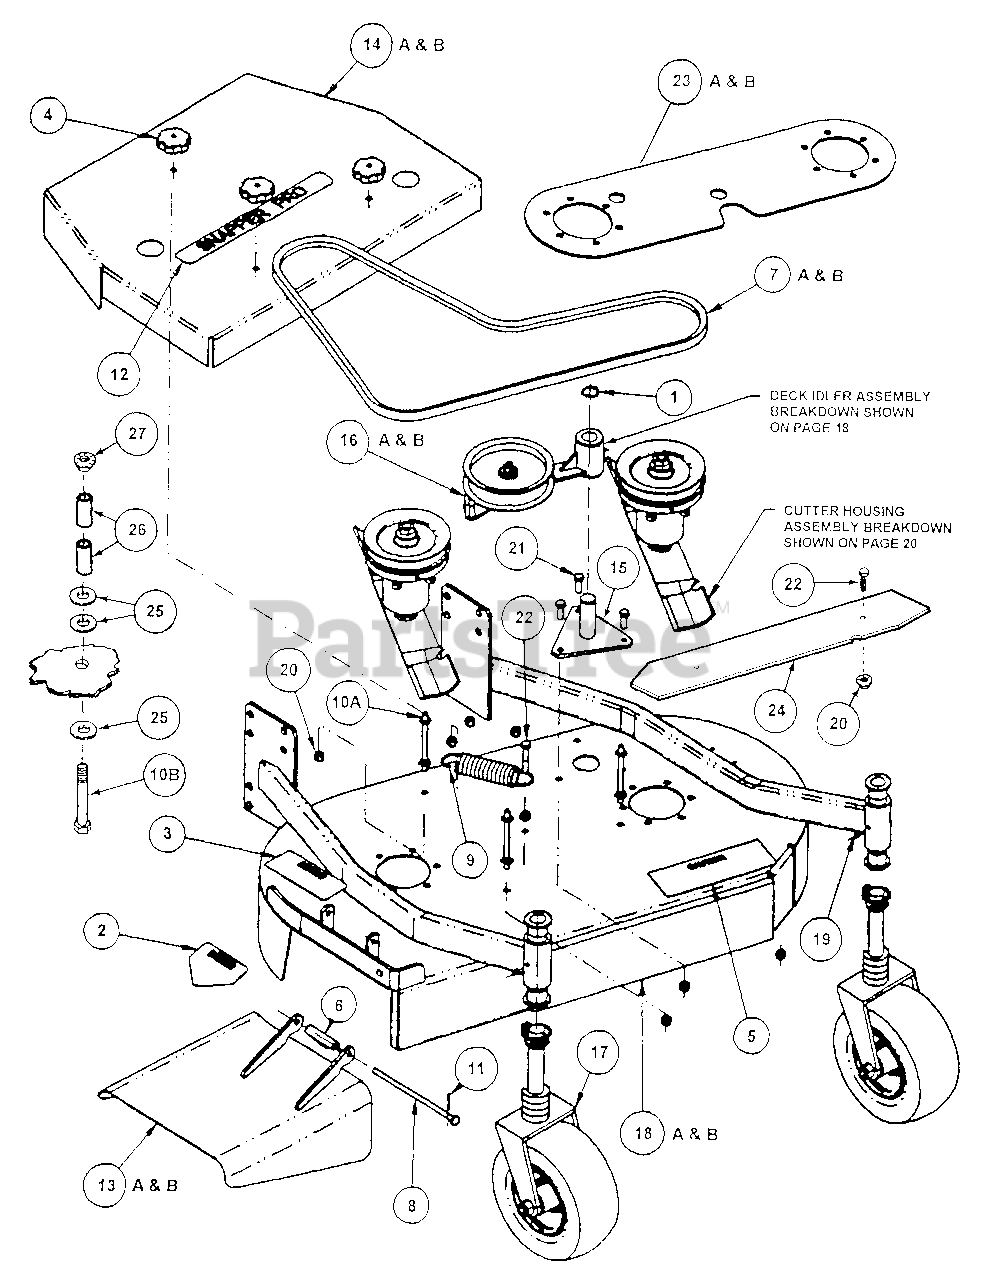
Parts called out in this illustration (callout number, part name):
1	SNAP-Ring, 1" External
2	DECAL, Warning (CPSC Cut Finger)
3	DECAL, Warning
4	KNOB, Hood
5	DECAL, Caution- Operator instruction
6	SPRING, Chute
7A	V-BELT, Deck Drive 36"
7B	V-BELT, Deck Drive 32"
8	HINGE PIN, Chute
9	SPRING, Idler
10A	STANDOFF, 3-1/2" (32" Deck)
10B	SCREW, 5/16-18 x 4-1/2" Gr. 5 H.H.C. (36" Deck)
11	PIN, 3/32 x 1" Cotter
12	DECAL, Snapper Pro
13A	DEFLECTOR, 36"
13B	DEFLECTOR, 32"
14A	COVER, 36"
14B	COVER, 32"
15	PIVOT, Idler (Weldment)
16A	ASSEMBLY, Idler Arm 36"
16B	ASSEMBLY, Idler Arm 32"
17	ASSEMBLY, Caster Red
18A	ASSEMBLY, Deck 36" Fixed Height
18B	ASSEMBLY, Deck 32" Fixed Height
19	FITTING, Lube 1/4-28 Straight
20	NUT, 3/8-16 HEX SERRATED FLANGE
21	BOLT, 3/8-16 X 1" GD5 CZ
22	BOLT, 3/8-16 X 2, GD5, CZ
23A	PLATE, Stiffener (7 Ga.) 36" Deck
23B	PLATE, Stiffener 32" Deck
24	PLATE, Ballast
25	WASHER, 3/8" I.D. Flat
26	SPACER
27	NUT, 5/16-18 Hex Flange Lock, Gr. 5
